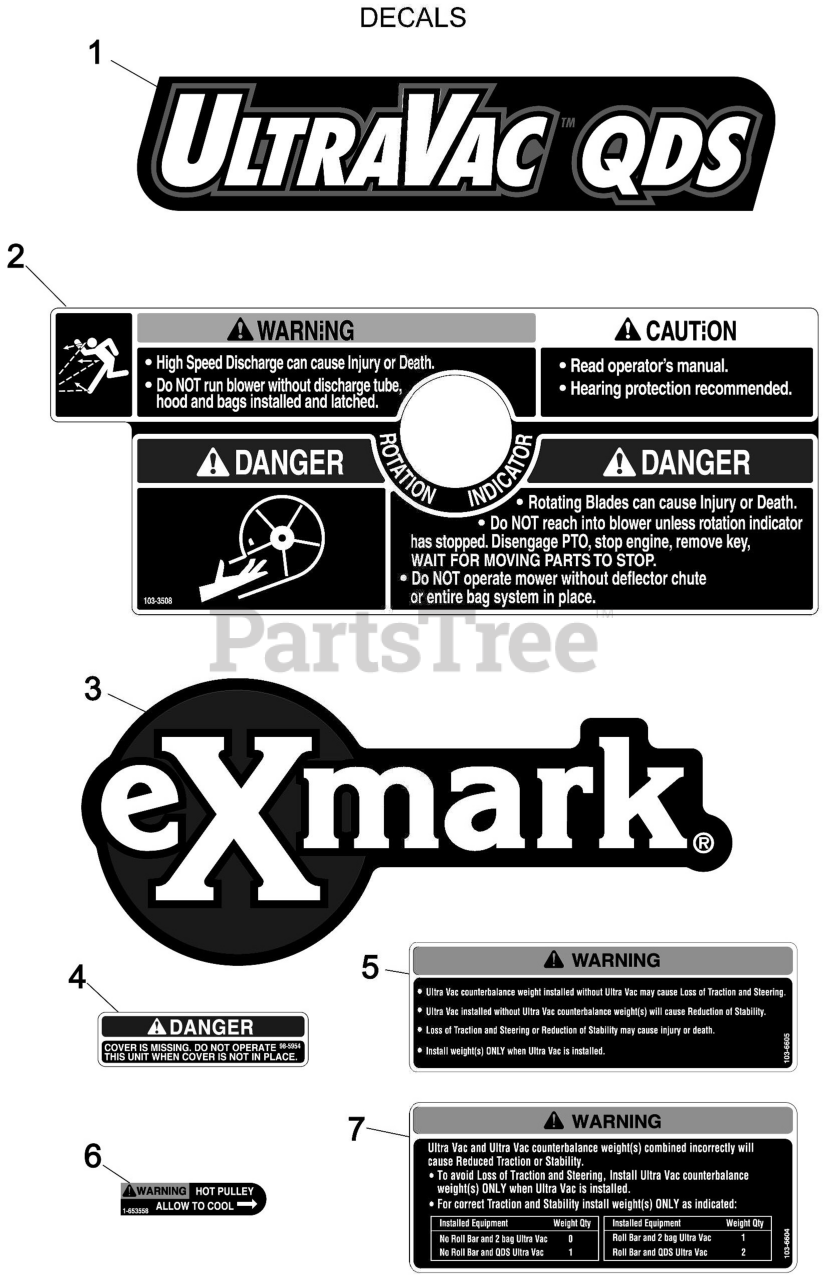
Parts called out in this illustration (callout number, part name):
1	DECAL, ULTRAVAC QDS
2	DECAL-WARNING
3	DECAL, EXMARK LOGO
4	DECAL-COVER, MISSING
5	DECAL,WEIGHT
6	DECAL-WARNING
7	DECAL,WEIGHT
